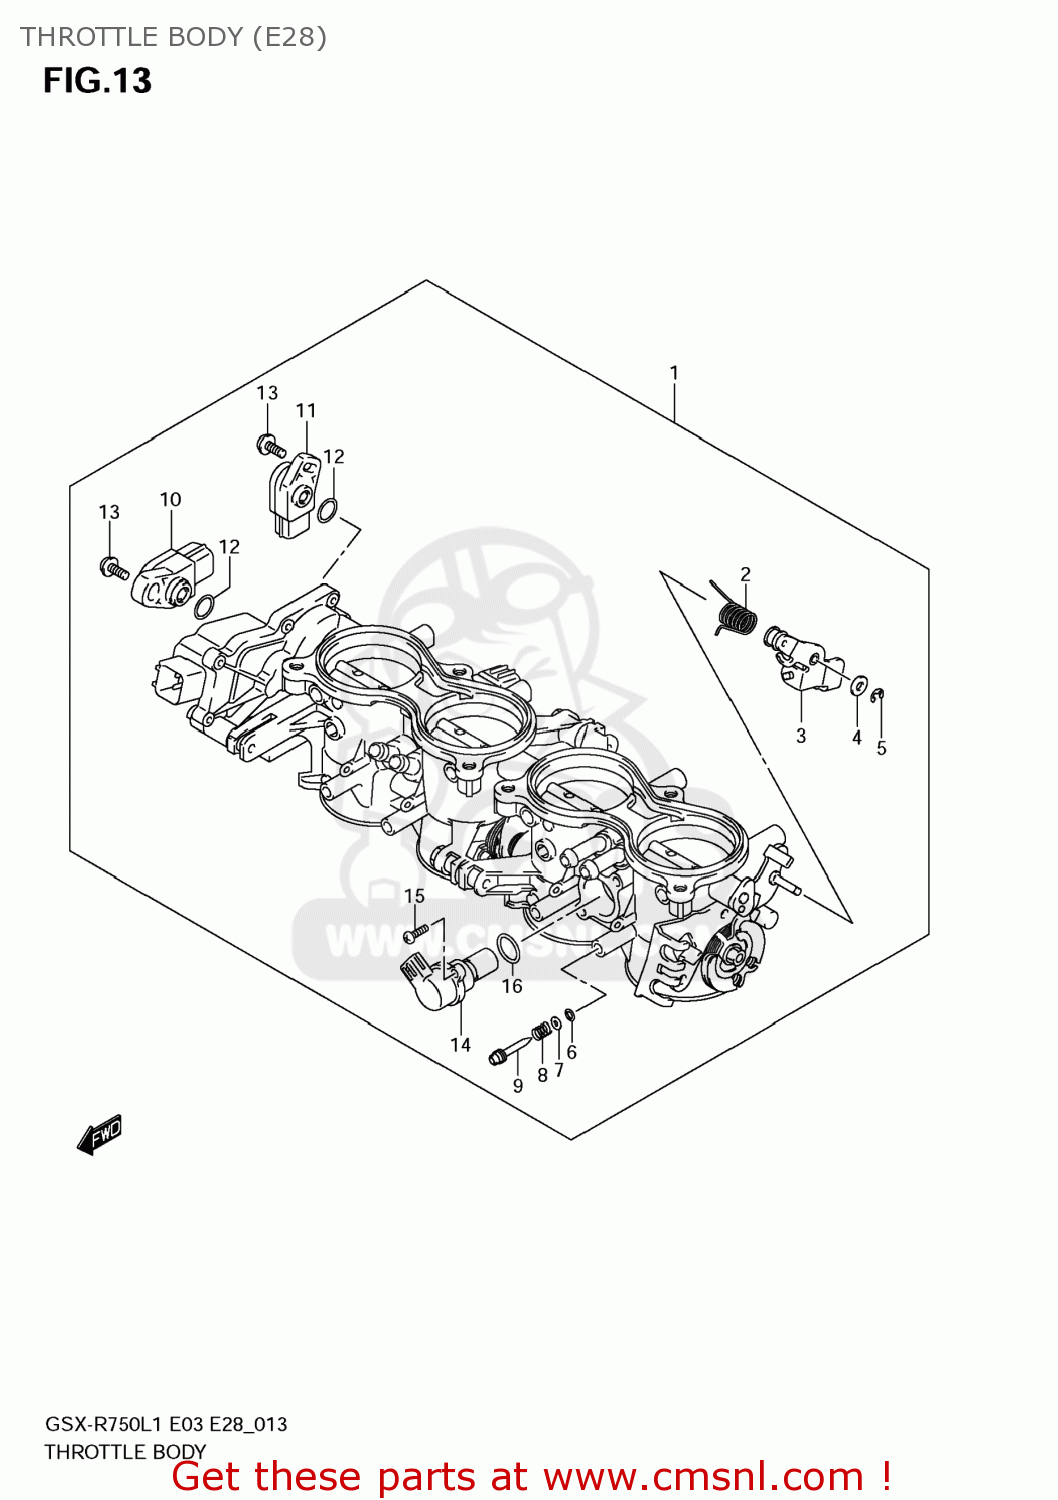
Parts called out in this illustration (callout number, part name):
1	BODY ASSY,THROTTLE
2	SPRING,TORSION
3	LEVER ASSY,LINK
4	PACKING (NAS)
5	E RING
6	O RING,PILOT AIR SCREW
7	WASHER
8	SPRING,THROTTLE SCREW
9	SCREW
10	SENSOR
11	SENSOR
12	O RING
13	SCREW
14	MOTOR ASSY
15	SCREW
16	O RING
